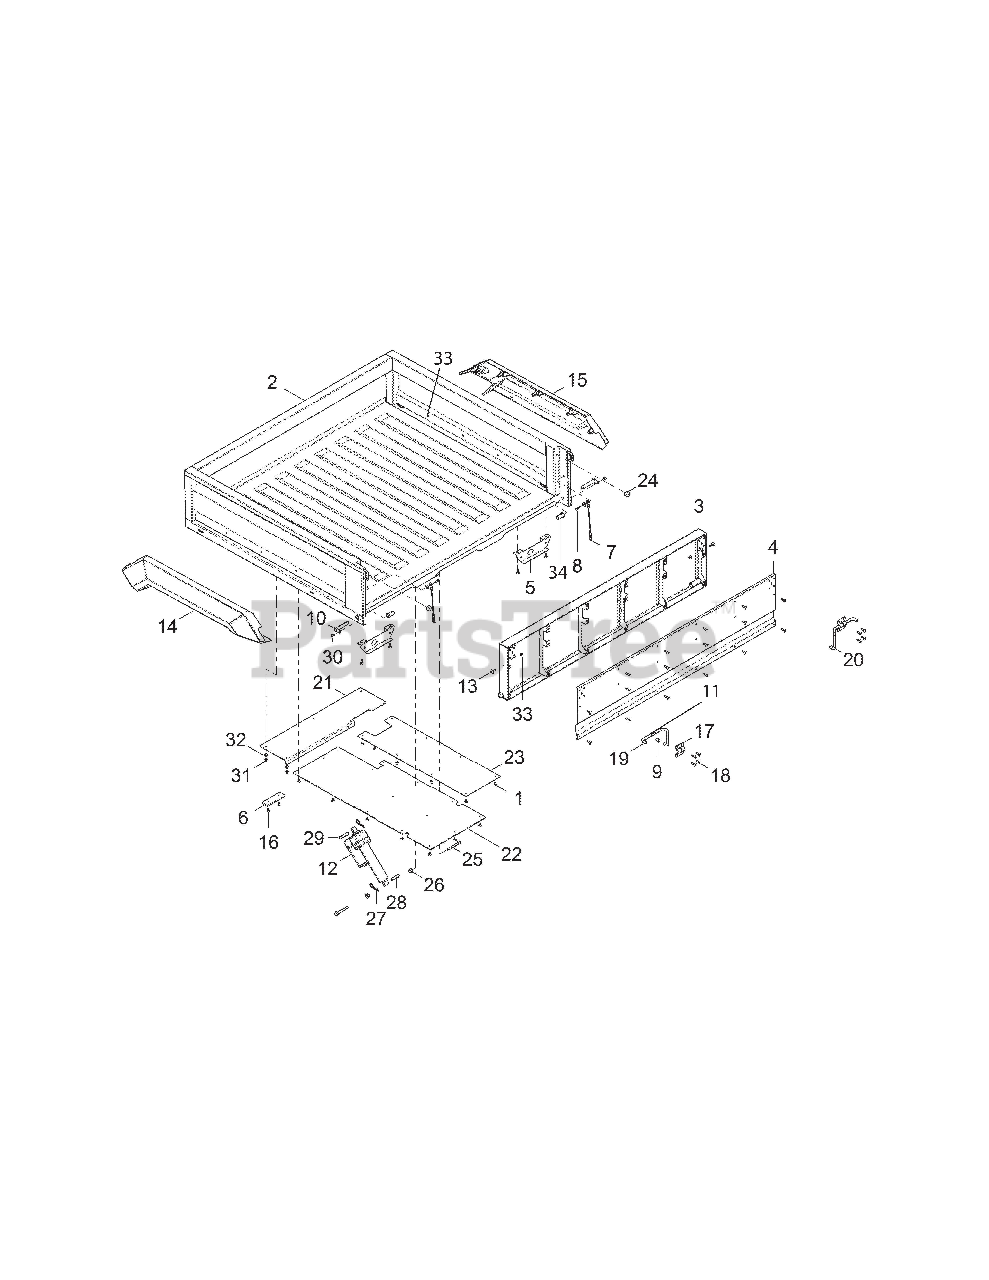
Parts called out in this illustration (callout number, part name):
1	RIVET(50) *
2	BOX-ARIENS,GRAVELY RED
3	TAILGATE,ARIENS,GRAVELY RED
4	PANEL, TAILGATE, GRAVELY RED
5	BRKT-TAIL LIGHT MOUNT
6	BUMPER-BOX BASE
7	CABLE, TAILGATE
8	BLT-SHLDR .188X.188X.25-20
9	CAP, TAILGATE LATCH
10	PIN-TAILGATE MOUNT
11	BUSHING, TAILGATE LATCH
12	ACTUATOR-BOX LIFT,SPLY
13	SCR-TXTH-M6X1.0X25 RIE,SHDR
14	ASM-FLARE,BOX,CLIP,LH
15	ASM-FLARE,BOX,CLIP,RH
16	NUT-M6 FLANGE,NYLOK
17	BRKT-TAILGATE LATCH
18	SCR-TXTH-M6X1.0X25 RIE
19	ROD, LATCH, LH, BLK
20	ROD, LATCH, RH, BLK
21	SHIELD, HEAT, EXHAUST, FRONT
22	SHIELD, HEAT, EXHAUST, REAR
23	SHIELD, HEAT EXHAUST MID
24	BUMPER, TAILGATE
25	SCR-HXFL-M10X1.25X80 8.8 ZOD
26	NUT-M10X1.25,FLG,NYLOC-OLIVE D
27	CLIP, HITCH PIN
28	PIN, CLEVIS
29	PIN, CLEVIS BOX LIFT 2"
30	SCR-M6X1X16 TR/TX-M
31	NUT-M6 FLANGE,NYLOK
33	SCR-TXPH-#14 X .75 HI-LO RIE
34	BUSHING, TAILGATE PIVOT PIN
